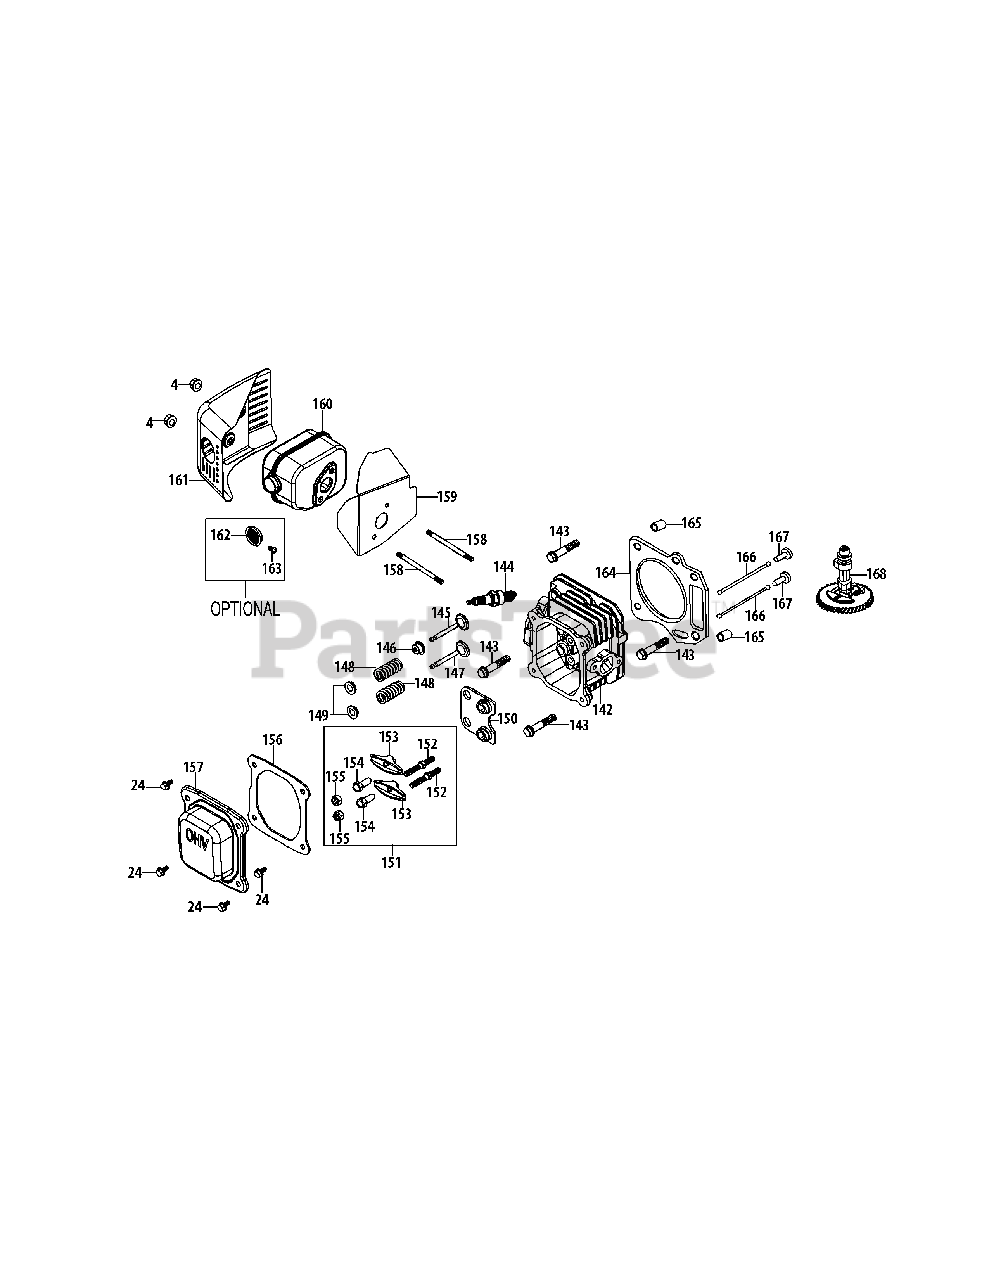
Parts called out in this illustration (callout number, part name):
4	Nut M6 X 10 Mm
24	Bolt M6×14
142	Cylinder Head
143	Head Bolt M8×54
144	Spark Plug
145	Intake Valve
146	Intake Valve Seal
147	Exhaust Valve
148	Valve Spring
149	Valve Spring Retainer
150	Push Rod Guide
151	Rocker Arm Assembly
152	Rocker Arm Stud
153	Rocker Arm
154	Fulcrum Nut
155	Jam Nut
156	Valve Cover Gasket
157	Valve Cover
158	Muffler Stud M6X95
158	Muffler Stud Assy
159	Muffler Gasket
160	Muffler Assembly
161	Muffler Shield
162	Spark Arrestor
163	Spark Arrestor Screw
164	Cylinder Head Gasket
165	Cylinder Head Dowel 10X16
166	Push Rod Kit
167	Tappet
168	Camshaft Assembly
